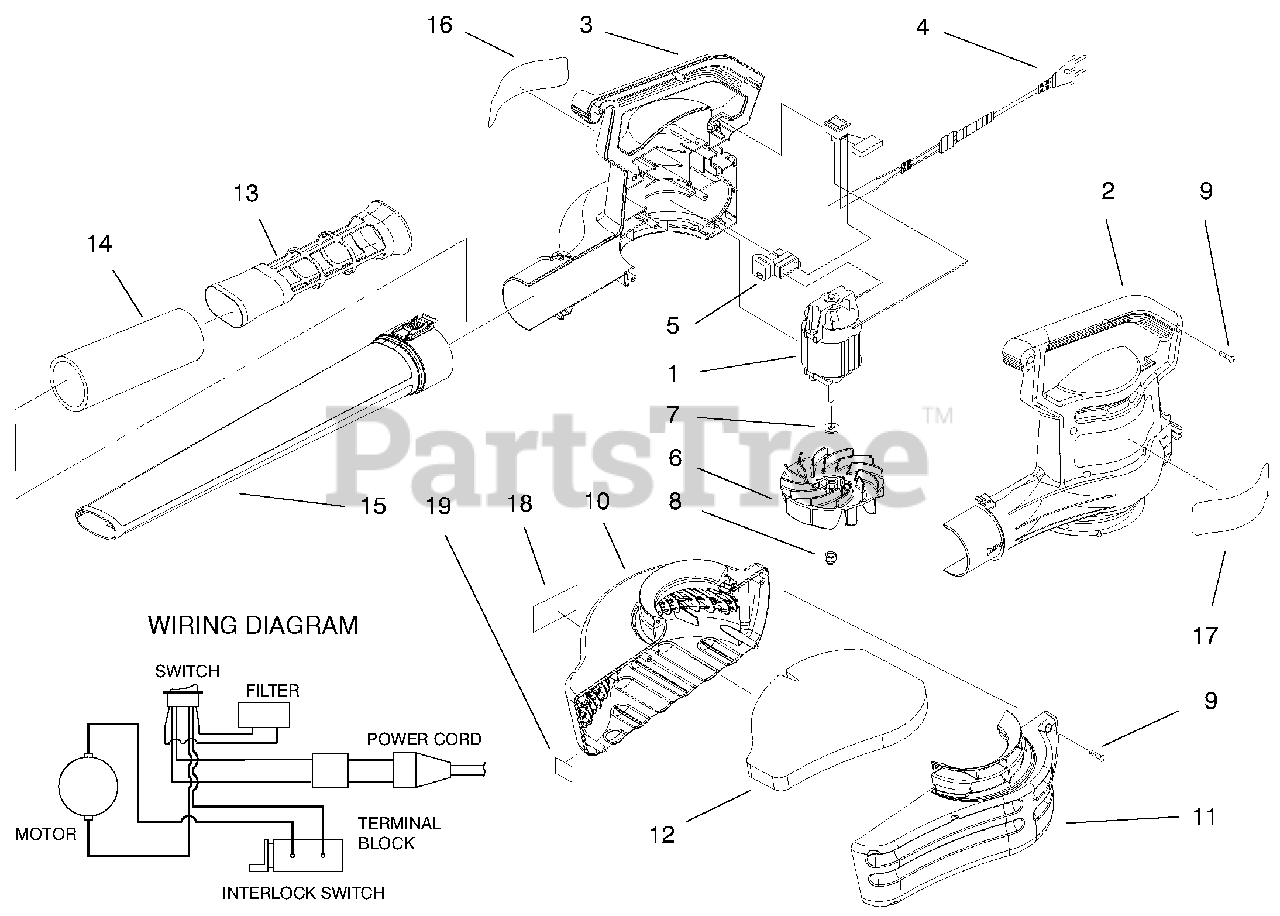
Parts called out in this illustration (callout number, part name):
2	Housing-L.H.
3	Housing-R.H.
4	Harness Assembly (Only On: 51566)
4	Harness Assembly (Only On: 51568)
5	Switch-Interlock
6	Impeller-Blower
8	Nut-Cap Hex
9	Screw-Phillips Hd. Tap.
10	Inlet-Quiet R.H.
11	Inlet-Quiet L.H.
12	Foam-Inlet
13	Insert-Quiet
14	Foam-Insert
15	Tube-Blower (Only On: 51566)
15	Tube-Blower (Only On: 51568)
16	Decal-Logo
17	Decal-Warning (Only On: 51566)
17	Decal-Warning (Only On: 51568)
18	Decal-QuieTech
19	Decal-63DBA
